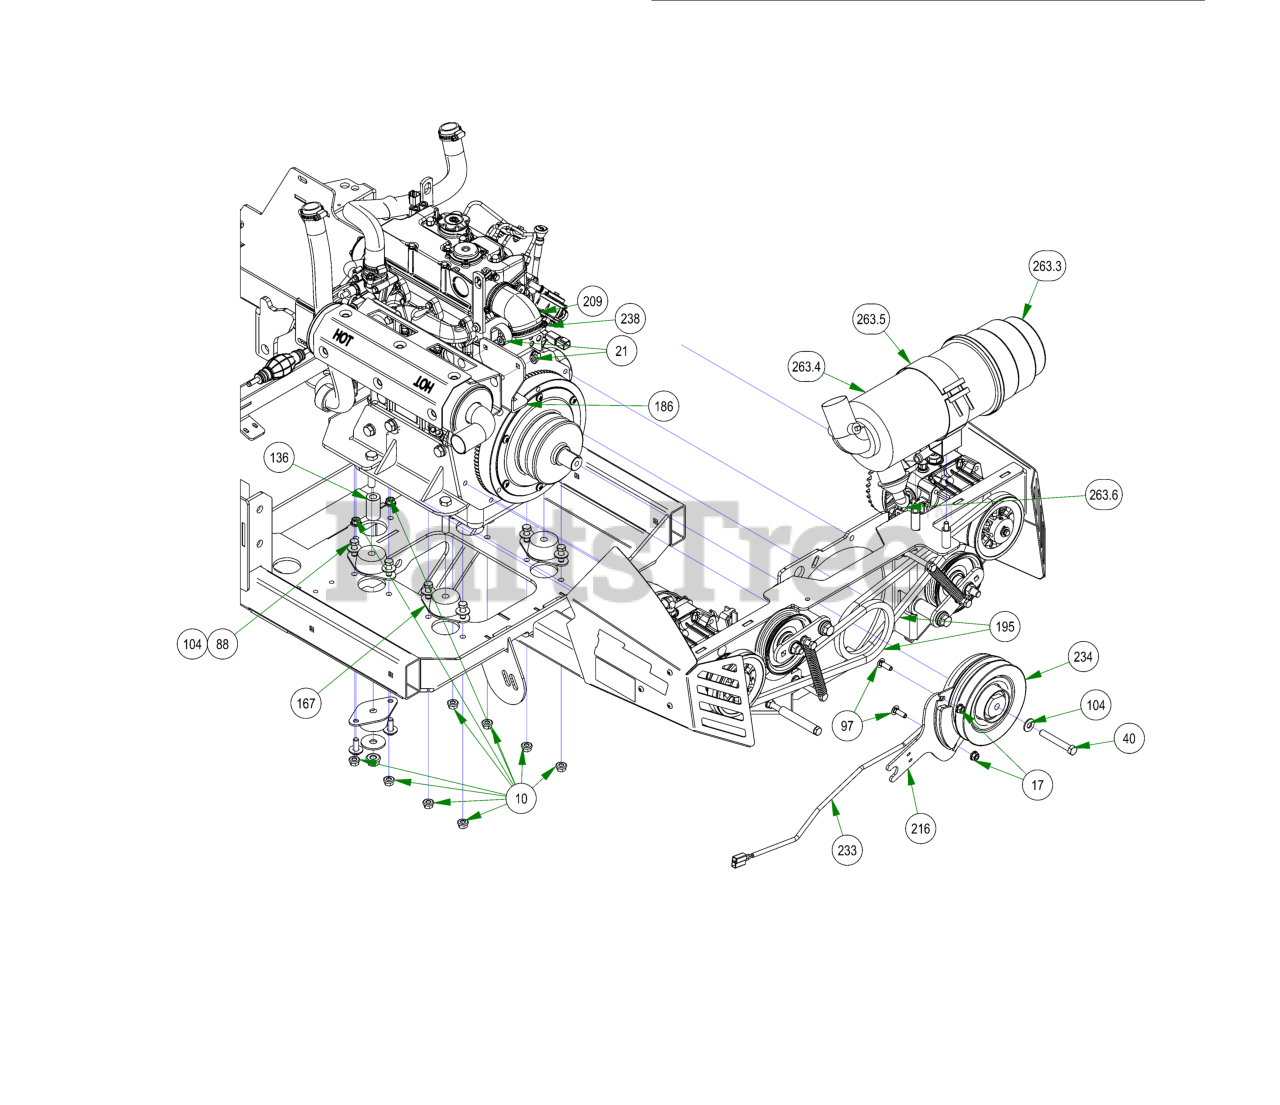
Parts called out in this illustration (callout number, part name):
10	3/8-16 NYLON INSERT FLANGE LOCKNUT (GR.F) ZINC
17	5/16-18 NYLON INSERT FLANGE LOCKNUT ZINC
21	5/16-18 HEX SERRATED FLANGE NUT HARD/ZINC
40	7/16-20x3” Hex Bolt GR 8 W/ Patch
44	5/16-18 X 2-1/4 HEX CAP SCREW (GR.5) ZINC
75	1/2-13 X 4 HEX CAP SCREW (GR.8) ZINC YELLOW
88	3/8-16 X 1 GR 5 Hex Bolts Zinc
99	M12-1.25 X 30MM DIN 961 HEX TAP BOLT (CL 8.8) ZINC
104	3/8 FLAT WASHER USS (1" OD) ZINC
129	.380 ID X .625 OD X 1.500 LGTH 2019 OUTLAW BRAKE HANDLE SPACER ZINC
136	1 3/4" Pulley Spacer
167	Rubber Compression Mount
171.1	5" Pump Pulley
171.2	5/16-24 X 1/2 SOCKET SET SCREW KNURLED CUP POINT
186	2019 Diesel Muffler Bracket
195	2020 Renegade Pump Belt, 42.99"
209	2019 Diesel Air intake Hose
216	2019 Outlaw Renegade Clutch Bracket
233	Clutch Pigtail
234	Clutch for Diesel/Vanguard
238	2-1/2" Hose Clamp
263	Enginaire Canister VLR-Complet
263.1	Diesel Air Filter- Outer
263.2	Diesel Air Filter- Inner
263.3	Enginaire Air canister cap
263.4	Canister for All Diesel Models
263.5	Mounting Bracket For Diesel Air Filter
263.6	Debris Plug-Enginaire Filter
